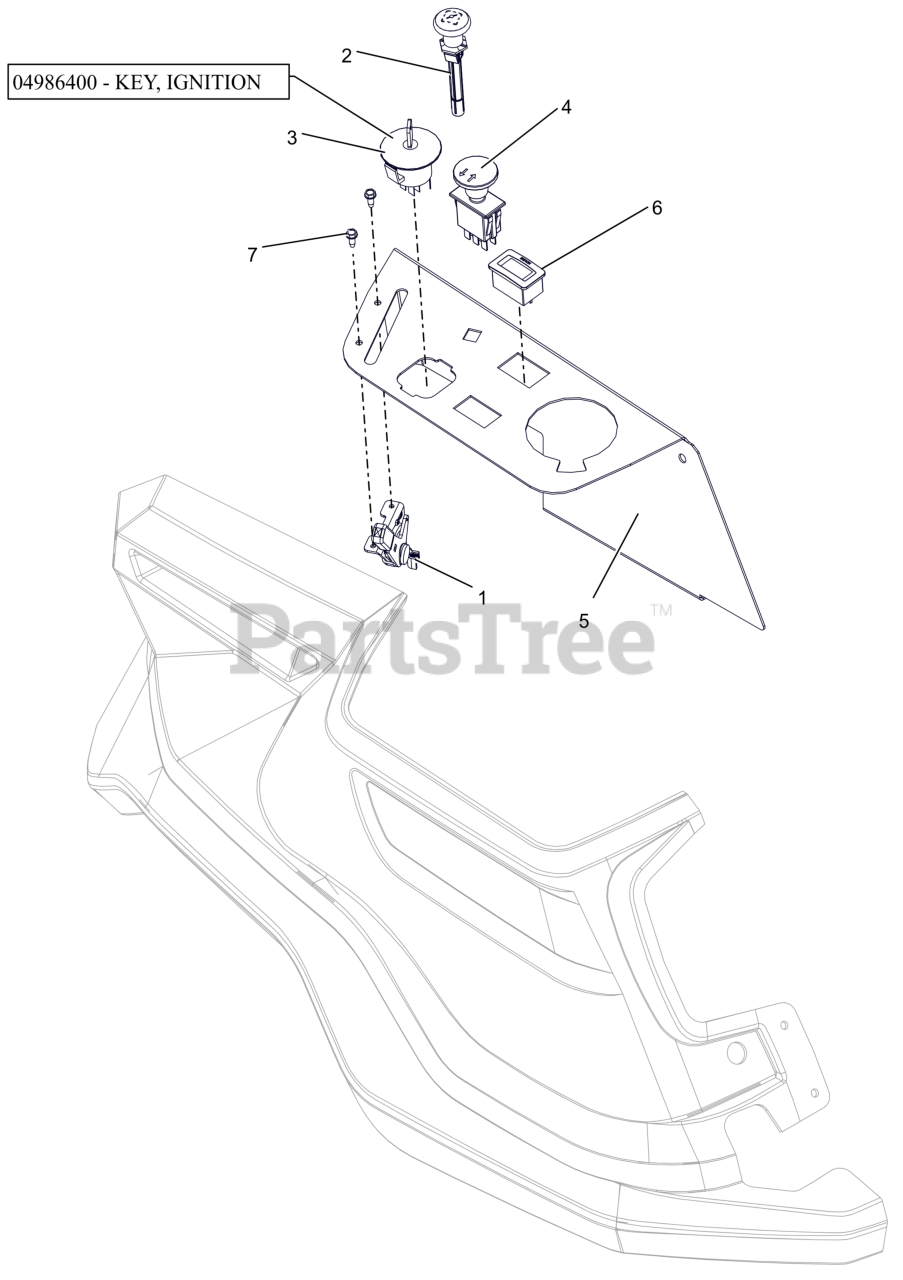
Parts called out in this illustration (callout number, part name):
1	CABLE - THROTTLE CONTROL
2	CABLE - CHOKE, SNAP-IN
3	KEYSWITCH-IGNITION 4 POS
3	KEY, IGNITION
4	SWITCH, CLUTCH (YELLOW)
5	PANEL, RIGHT SIDE FENDER MOUNT
6	HOUR METER
7	SCR,TAP #10-24X.50 HWH TR ZCC
